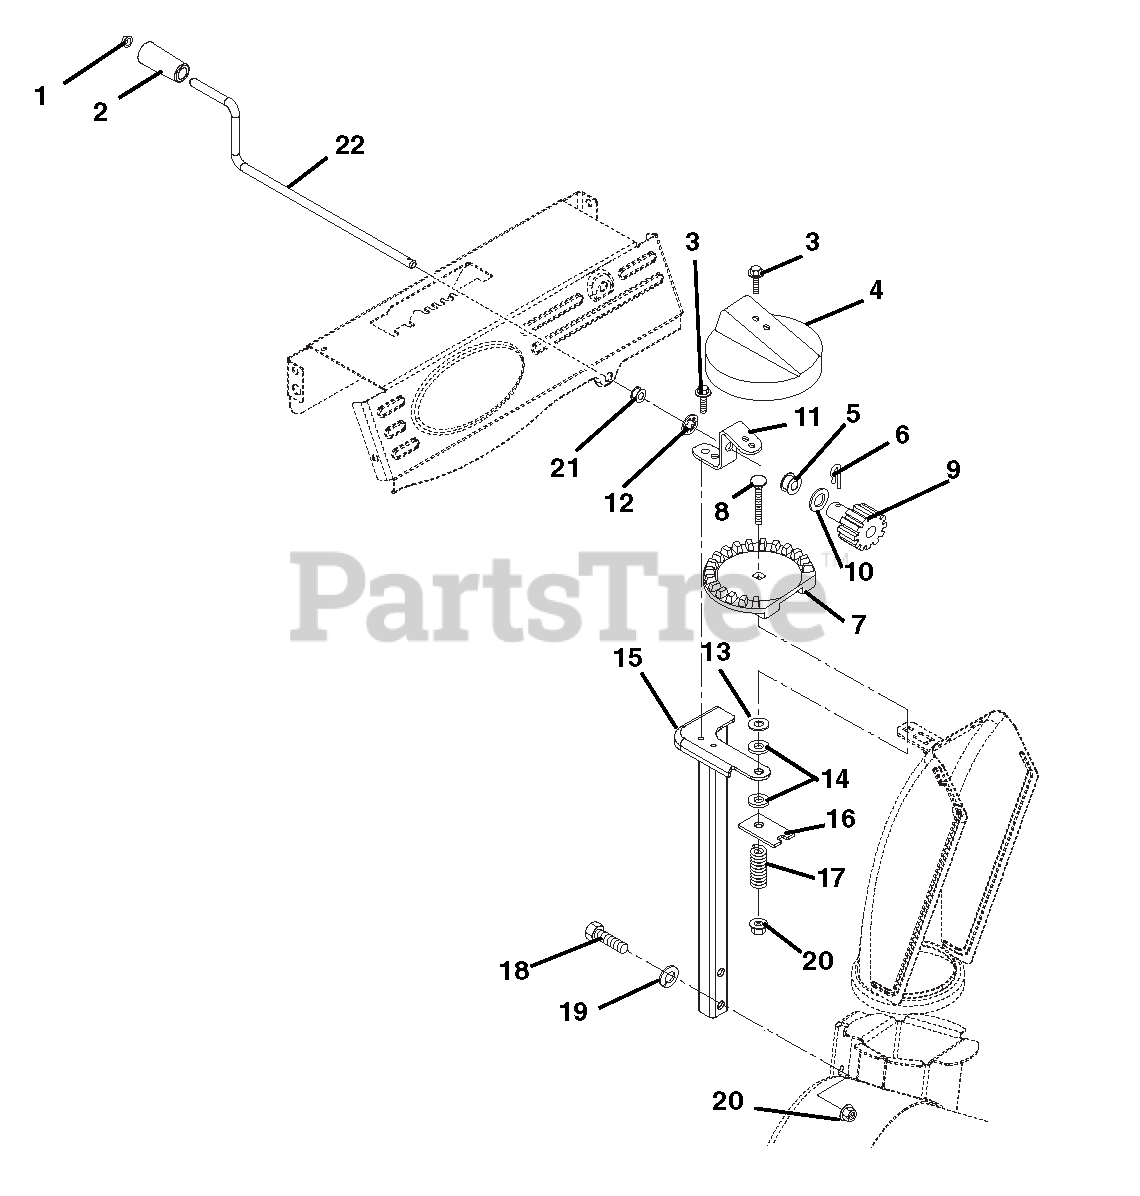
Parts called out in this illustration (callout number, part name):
1	CAP, 3/8 ROD YWZC
2	KNOB, CHUTE CRANK
3	SCR-TAP .25-20X.50 HWH TR YWZ
4	GEAR COVER
5	BUSHING, POLYLINER-.63 SNAPIN
6	PIN, SPRING CLIP
7	CHUTE GEAR
8	@BLT-RDHDSQNK .38-16X2.50 G5YZ
9	PINION GEAR W/BRACKET
10	WSHR-THRST .625 X 1.0 X .03
11	BRACKET, PINION GEAR
12	PUSHNUT .625
13	WSHR-FL-STL .380X1.50X.062 YWZ
14	FRICTION WASHER
15	CHUTE PEDESTAL, TALL COMPACT
16	PLATE, FRICTION
17	SG-COMP .187X.56X1.62
18	@BLT-HEX .38-16X1.75 GR5 YWZC
19	@WSHR-LK .38X.094 REG YWZC
20	@NUT-LK-TOP-FLG .38-16 YWZC
21	BUSHING, POLYLINER-.38 SNAPIN
22	CHUTE CRANK,COMPACT 920,XXX HI
